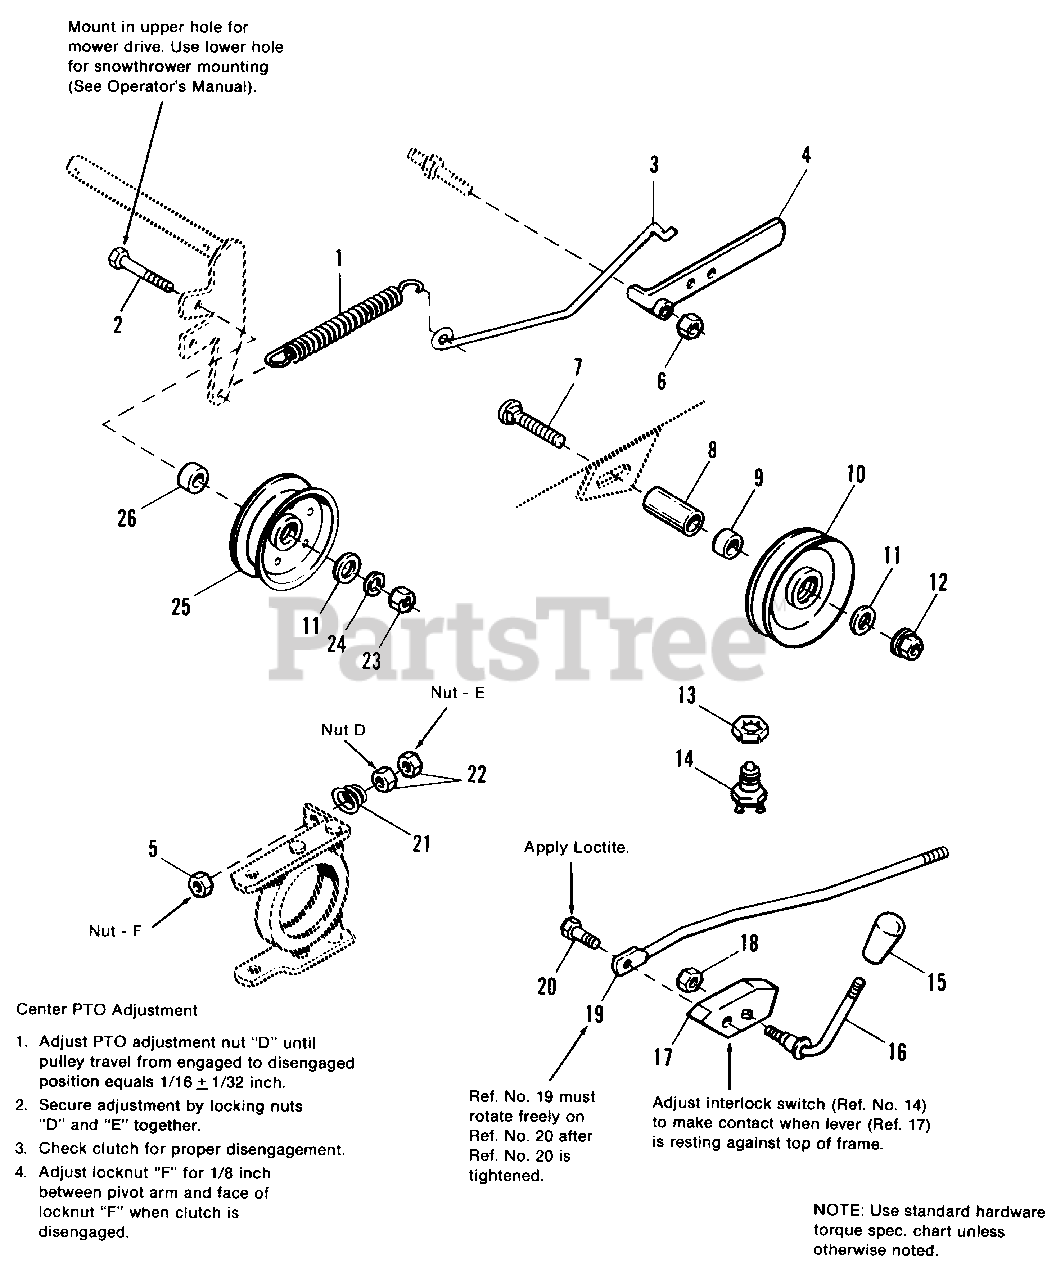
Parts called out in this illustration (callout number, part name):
1	SPRING, Tension
2	CAPSCREW, Hex Hd., 3/8-16 x 2
3	ROD, Tension
4	HANDLE ASSY.
5	LOCKNUT, Hex, Jam, Cntr. 5/16-18
6	LOCKNUT, Hex, 7/16-14
7	BOLT, Carriage, 3/8-16 x 1-3/4
10	PULLEY ASSY., w/Bearings
11	WASHER, Plain, 3/8
12	LOCKNUT, Whizlock, Flange, 3/8-16
13	NUT, Pal
14	SWITCH, Interlock
15	KNOB
16	HANDLE, PTO, Clutch
18	LOCKNUT, Hex, 3/8-16
19	ROD ASSY., Control
20	CAPSCREW, Special
22	NUT, Hex, Full, 5/16-18
23	NUT, Hex, Full, 3/8-16
24	LOCKWASHER, 3/8
25	PULLEY, Idler
